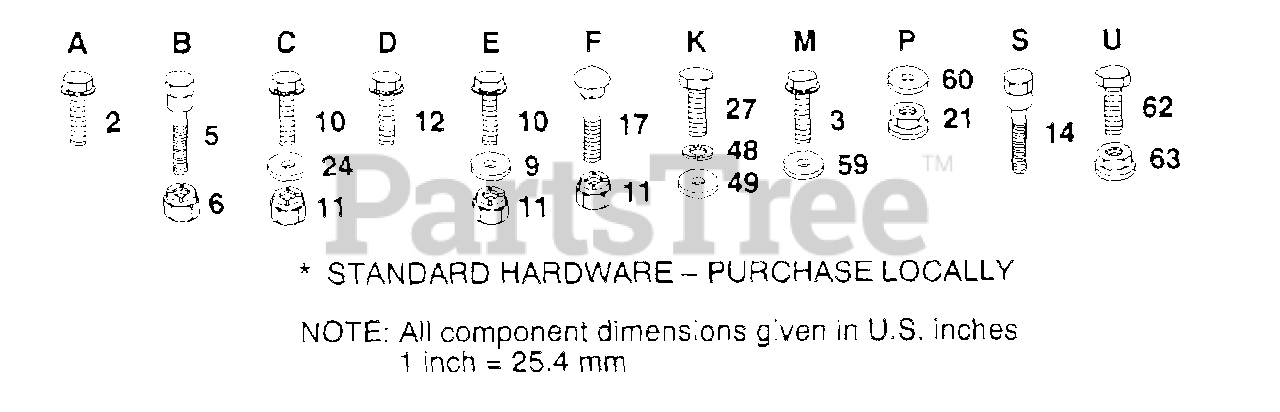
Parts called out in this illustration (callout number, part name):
2	SCREW
3	SCREW GTV
7	SPRING COMPRESSIO
9	WASHER
12	SCREW LT
14	"BOLT,SHOULDER"
17	BOLT
21	PAL NUT LT
24	WASHER
27	BOLT
48	LOCKWASHER
49	WASHER
59	WASHER
60	WASHER PM
62	BOLT
